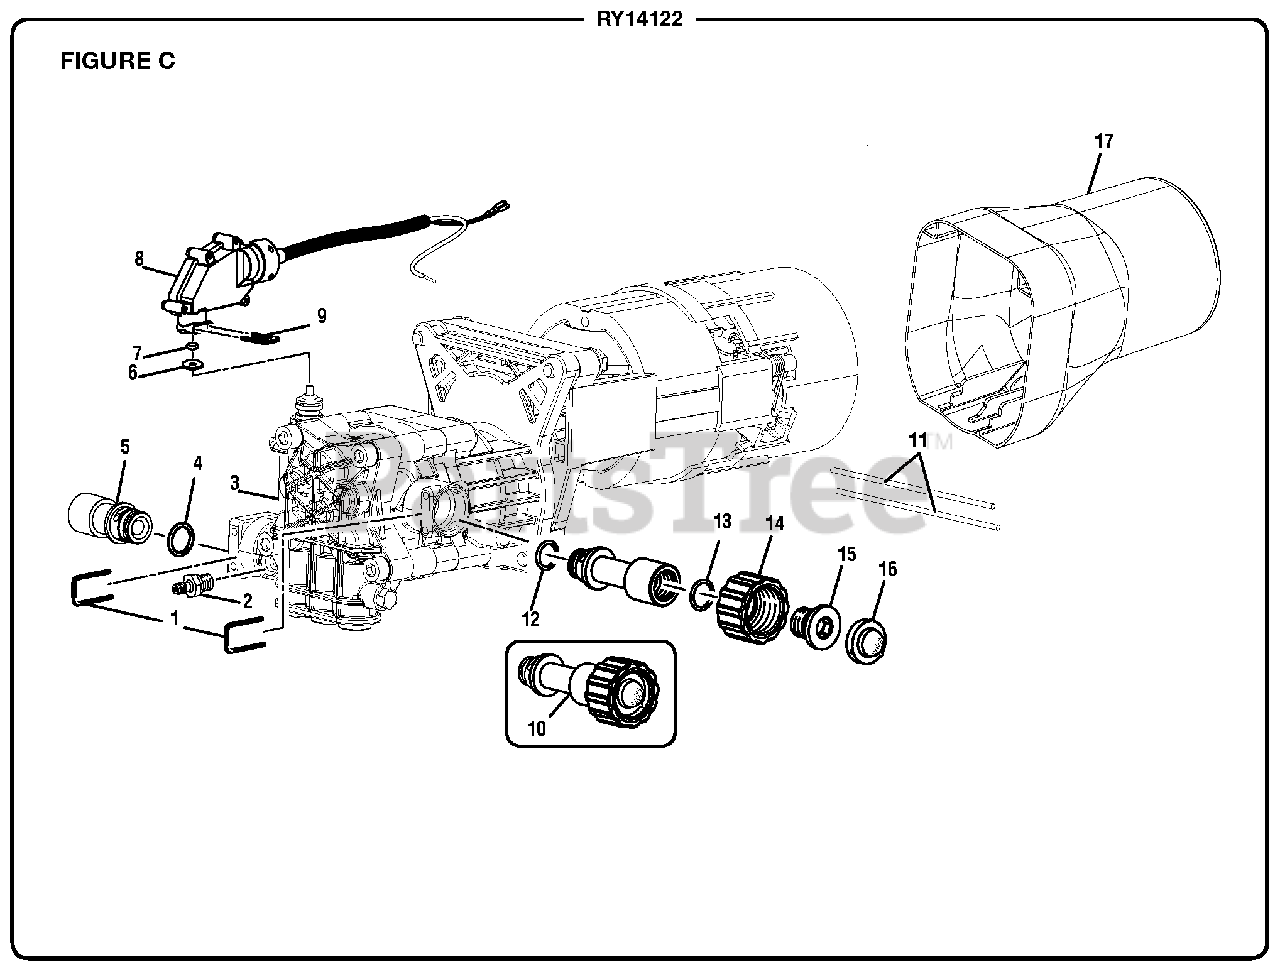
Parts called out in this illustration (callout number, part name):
2	Detergent Nipple Assembly
5	Outlet Tube Assembly
6	Washer (Brass)
7	O-Ring
8	Pressure Switch
10	Inlet Tube Assembly
14	Water Inlet Connector
15	Water Inlet Screw Nut
16	Water Inlet Filter
17	Air Shourd
